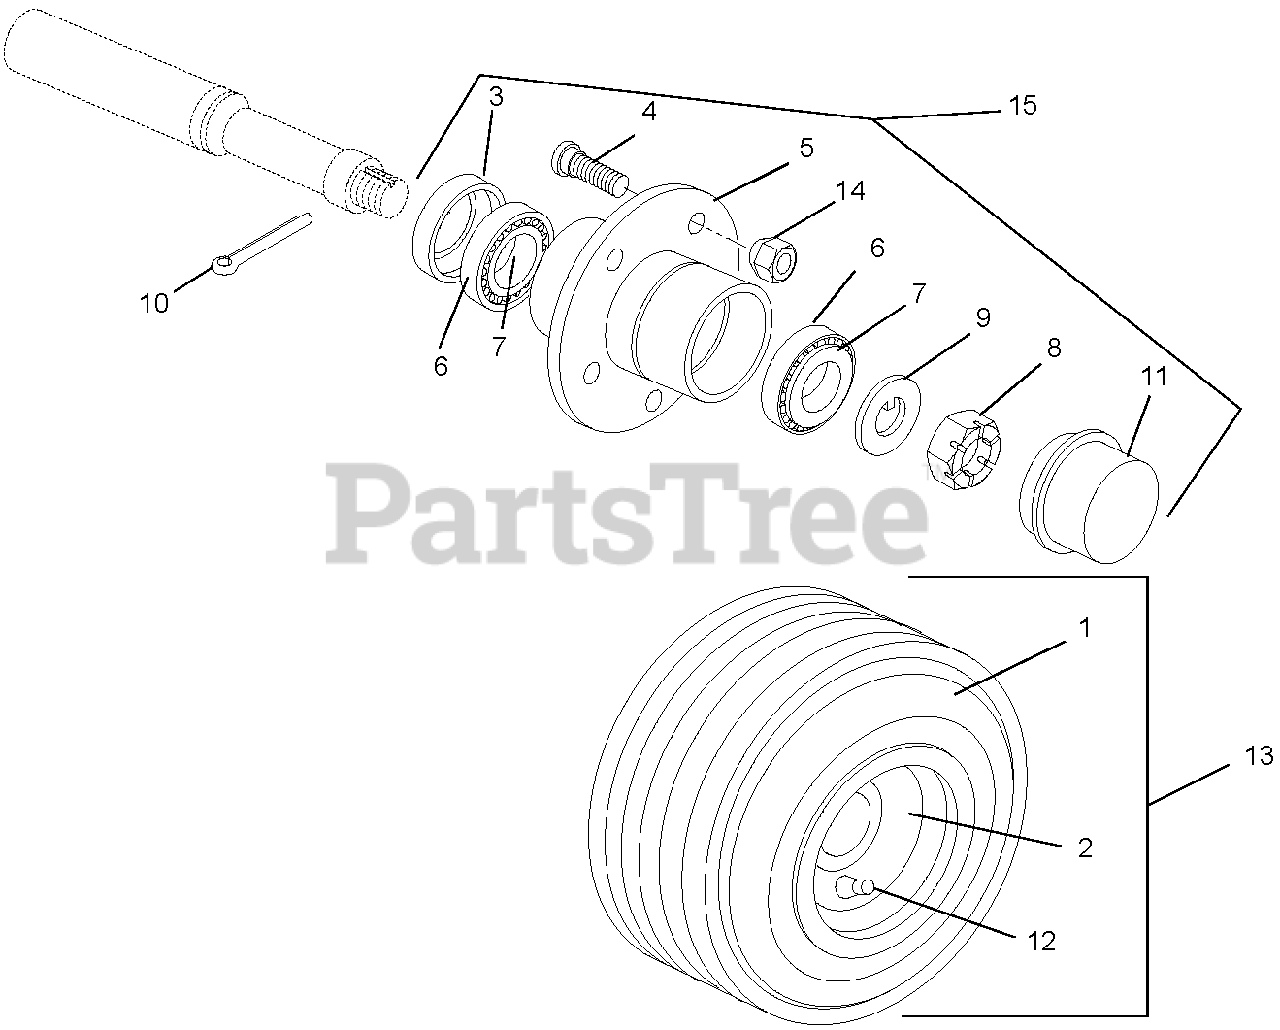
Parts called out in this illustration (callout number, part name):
1	Tire 18 x 8.5 x 8
2	Wheel, 8 x 7, 5-Hole
4	Bolt, Lug .50-20 x 1.875
5	Hub, Includes Bolts and Bearing Cup
6	Cup, Bearing 1.9687 O.D. x .420
7	Cone, Bearing 1.000 Bore x .5
8	Nut, Hex .75-16 CP Castellated
9	Washer, Axle Left
10	Pin, Cotter .125 x 1.25
11	Cap, Hub
12	Valve Stem, TR-412
13	Tire And Wheel Assembly 18 x 8.5 x 8
14	Nut, Hex Hub .50-20 UNF
15	Hub Assembly, 5-Bolt
